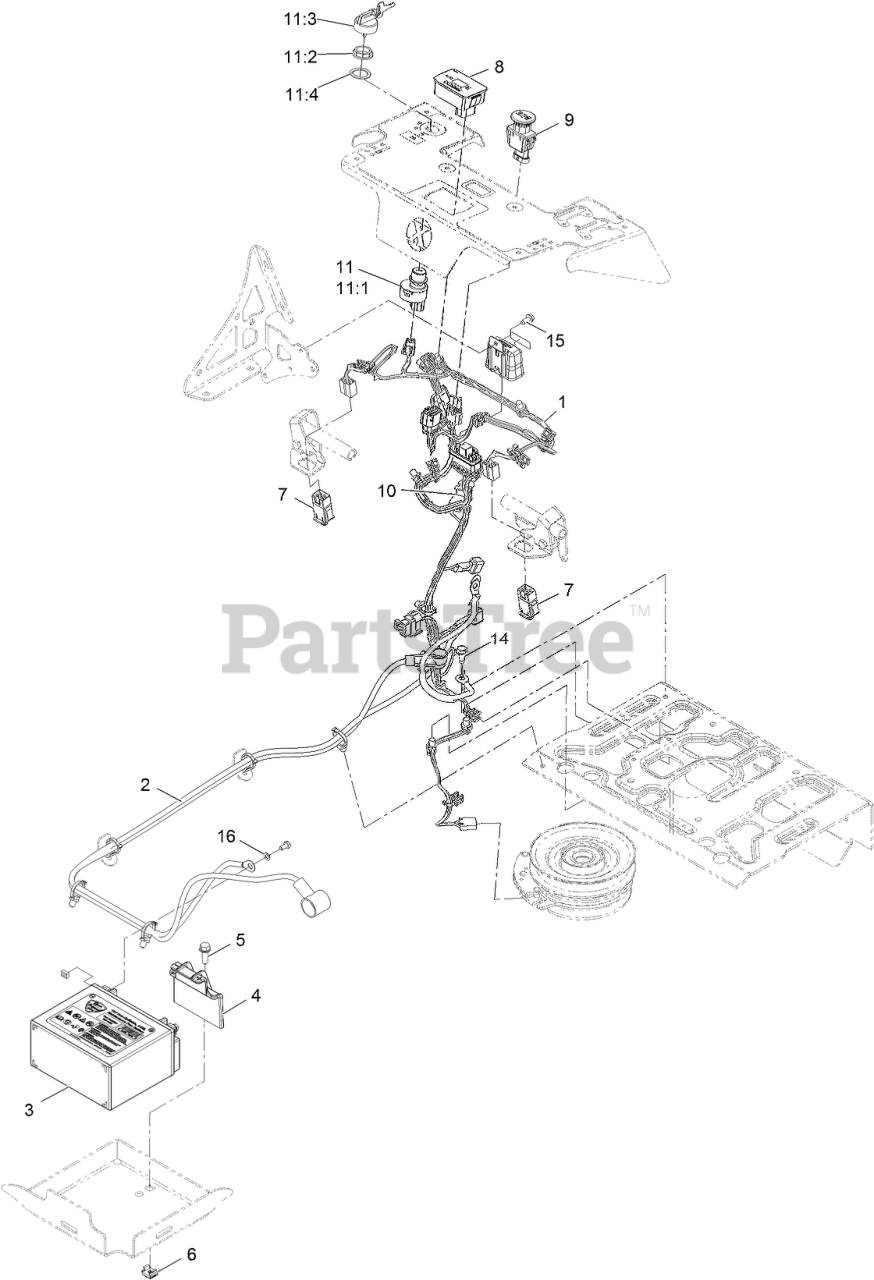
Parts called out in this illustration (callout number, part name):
1	HARNESS-WIRING
2	Harness-Battery
3	Battery, Agm
4	Hold Down, Battery
5	SCREW-HHF
6	Nut, Snap
7	SWITCH-DELTA
8	Module-Hour Meter
9	SWITCH-PTO, SEALED
10	SWITCH-BAIL
11	IGNITION SWITCH ASM
11:1	Switch-Ignition
11:2	NUT-MOUNTING
11:3	IGNITION KEY SET
11:4	WASHER-BACKUP
14	SCREW-THD ROLL, HWH
15	SCREW-HWH
16	WASHER-SPRING
